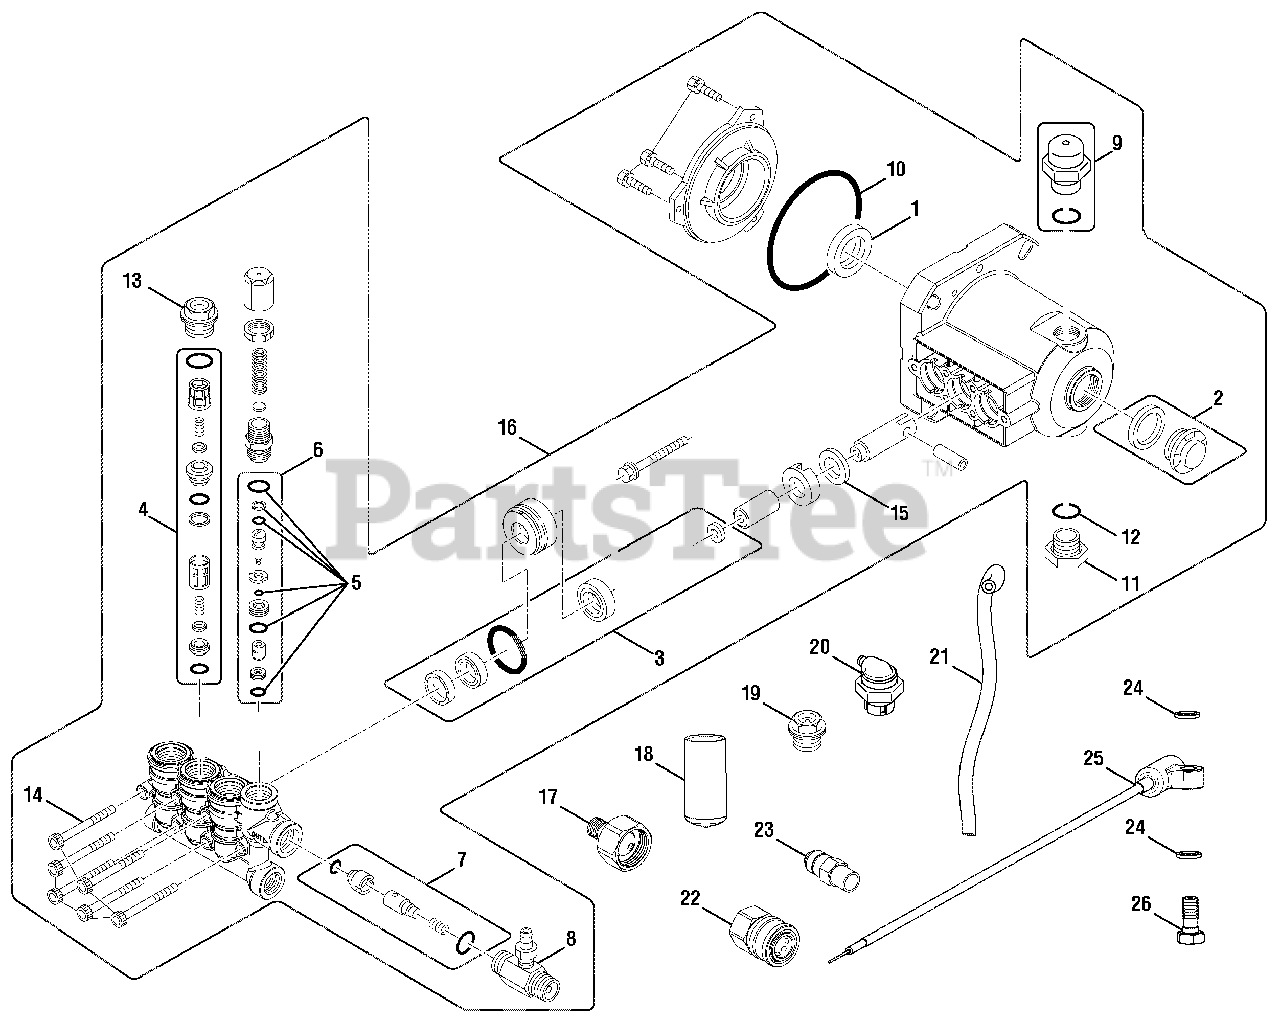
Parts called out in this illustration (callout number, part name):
1	Oil Seal
3	Seal Kit
4	Valve Assembly
5	O-Ring Kit
6	Unloader Kit
7	Check Valve Kit
8	Fixed Injector
9	Oil Fill Cap w/O-Ring
11	Drain Plug
15	Oil Seal
16	Pump Assembly (4GXT30, Inc. Key Nos. 1-15)
17	Garden Hose Coupler w/Filter
18	Unloader Cap
19	Idle Down Plug
20	Vent Cap
21	Vent Tube (11 in.)
22	Quick Connect (3/8 in.)
23	Thermal Release Valve
24	Compression Seal
25	Throttle Control Assembly
26	Bolt (M10 x 1.5 in., Special)
